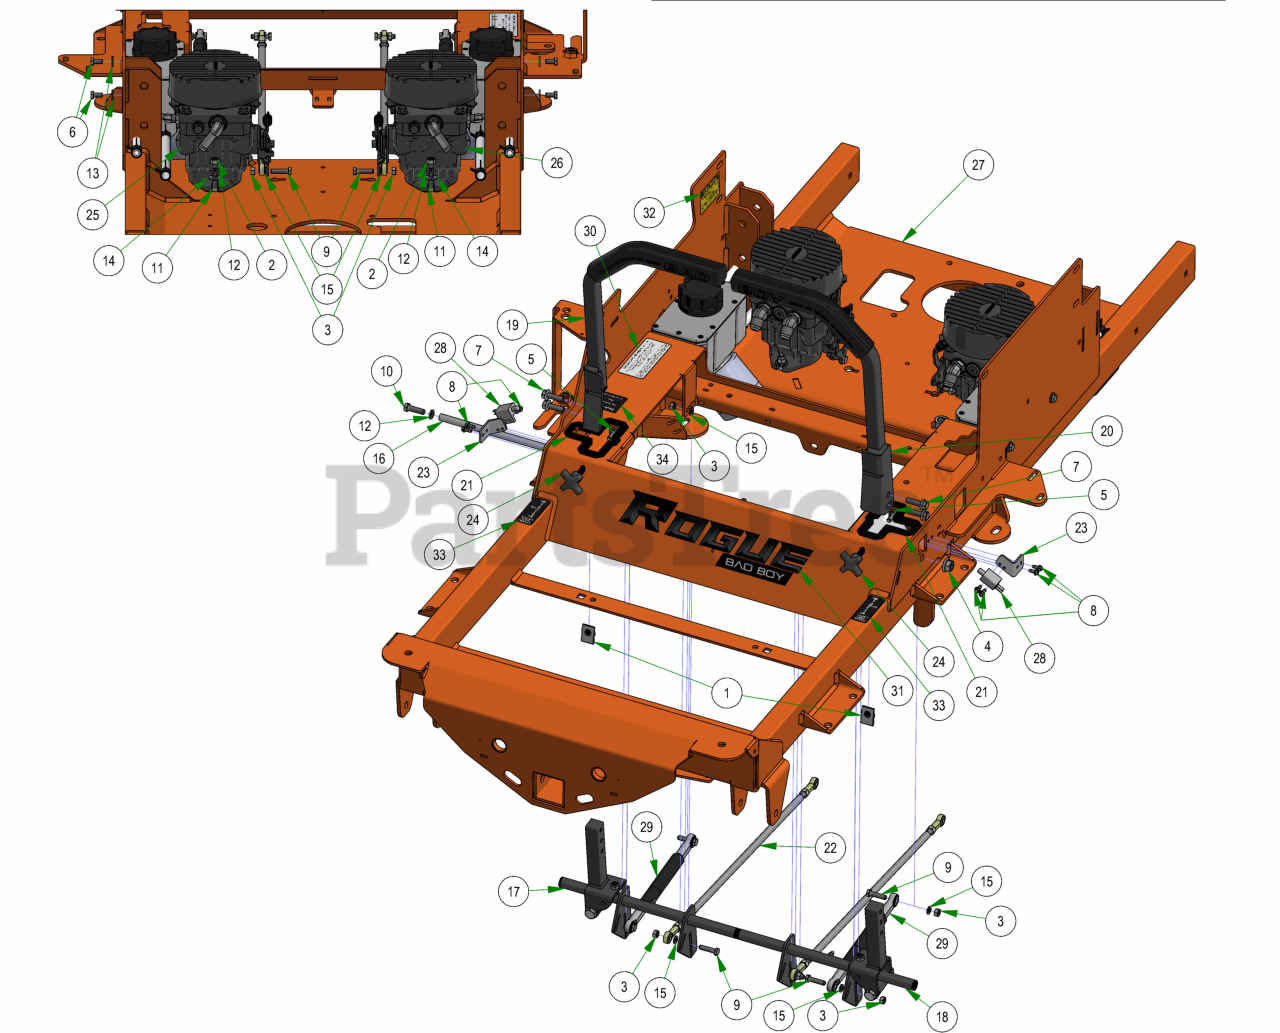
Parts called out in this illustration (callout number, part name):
1	Extruded Nut 3/8"-16 3/4" Hole Center With Patch
2	3/8-16 HEX NUT ZINC
3	5/16-18 HEX NUT ZINC
4	1/2-13 NYLON INSERT FLANGE LOCKNUT ZINC
5	5/16-18 HEX SERRATED FLANGE NUT HARD/ZINC
6	5/16-18 x 5/8 Hex Bolt
7	3/8-16 X 1 1/4 HEX WASHER UNSLOT MACHINE SCREW ZINC GR5
8	12-24 X 1/2 HEX WASHER UNLSOT F TCS ZINC
9	5/16-18 X 1-1/4 HEX C/S (GR.5) ZC
10	3/8-16 X 1-1/4 HEX CAP SCREW (GR.5) ZINC
11	3/8-16 X 1-1/2 HEX CAP SCREW (GR.5) ZINC
12	3/8 SPLIT LOCKWASHER ZINC
13	1/4 USS FLAT WASHER (3/4 OD) ZINC
14	5/16 USS FLAT WASHER (7/8 OD) ZINC
15	5/16 SPLIT LOCKWASHER ZINC
16	2019 Steering Actuator Rod
17	R Series Square Drive Arm Actuator RH Assembly
18	R Series Square Drive Arm Actuator LH Assembly
19	R Series Square Drive Arm RH Assembly
20	R Series Square Drive Arm LH Assembly
21	Snap-in Drive Arm Bushing
22	2019 Outlaw Gen2 XP Push Rod Assembly
23	2019 Arm Switch Bracket
24	Speed Limiting Knob 3/8-16X 3"
25	2021 LH ROGUE HYDRO TANK LINE ASSY
26	2021 RH ROGUE HYDRO TANK LINE ASSY
27	2023 Rogue Frame - Painted
28	Safety Switch
29	2019 SROID Damper With Spherical Rod Ends
30	2024 EPA Build Date Punch Decal
31	Rogue back Plate & Front Decal
32	Hydraulic Decal
33	2018 LH/RH Steering Control Decal Roll
34	2019 Deck Release Decal
